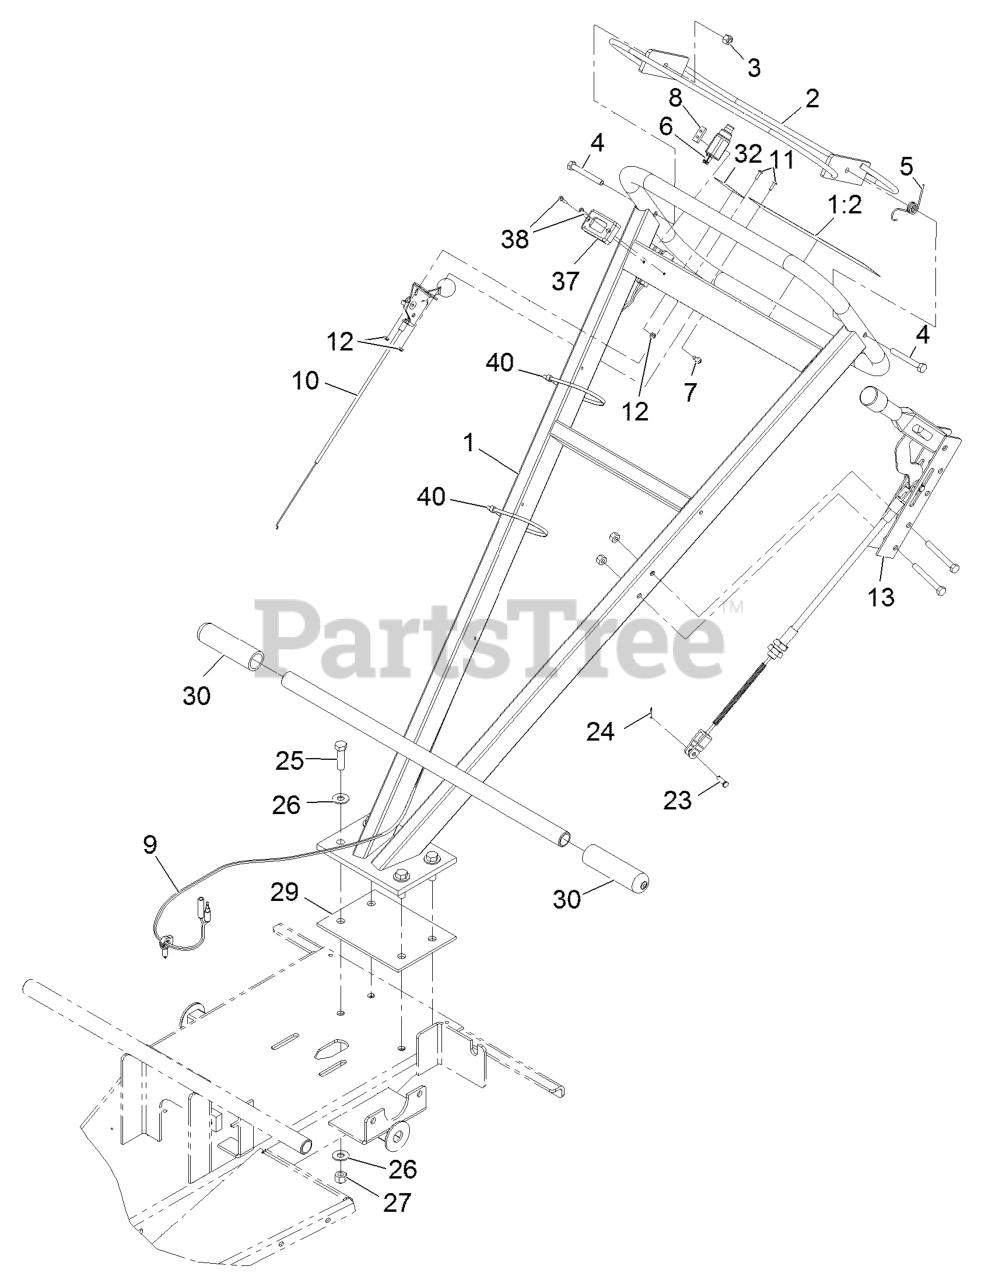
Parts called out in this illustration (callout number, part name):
1	HANDLE ASM
1:2	DECAL-WARNING
2	HANDLE-SAFETY
3	NUT-LOCK, NI
4	SCREW-HH
5	SPRING-RETURN
6	SWITCH-PLUNGER, NO (W/COV
8	PLATE-TAPPED
9	HARNESS-WIRE
10	CABLE-THROTTLE
11	SCREW-PRH
12	NUT-HEX
13	BRAKE LEVER ASM
23	PIN-CLEVIS
24	PIN-COTTER
26	WASHER-FLAT
27	NUT-LOCK, NI
29	GASKET-HANDLE
30	GRIP-HANDLE
32	DECAL-ENGAGE
37	HOURMETER-INDUCTIVE
38	SCREW-PPH
40	TIE-CABLE
